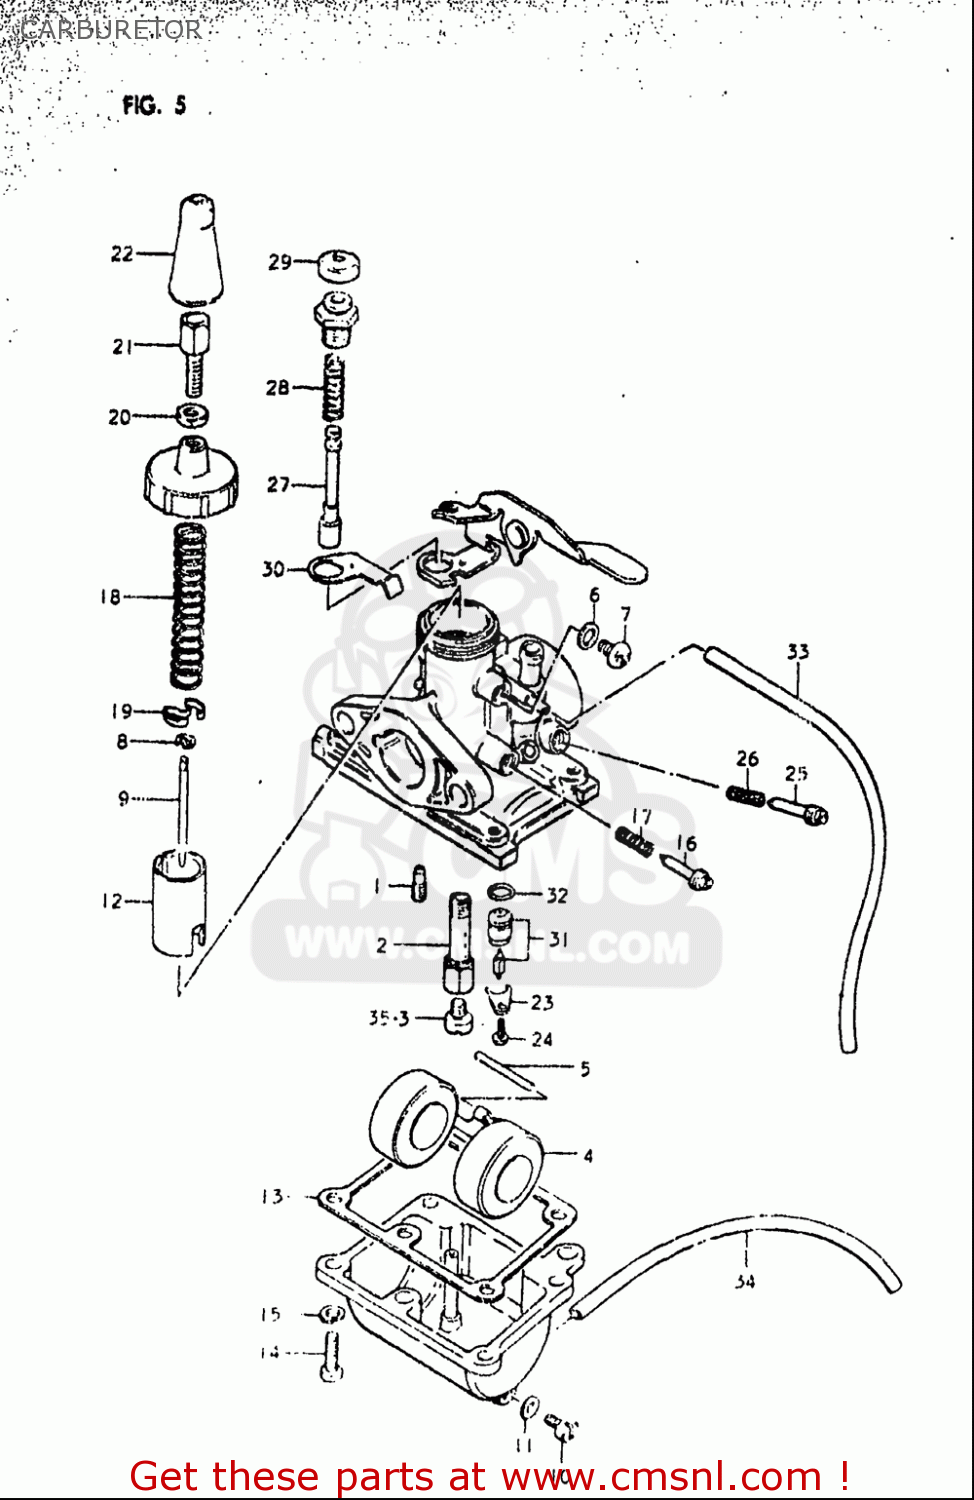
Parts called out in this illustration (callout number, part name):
1	JET,PILOT(15)
2	JET,NEEDLE
3	JET,MAIN(75)
4	FLOAT
5	PIN,FLOAT
6	GASKET,DRAIN PLUG (NAS)
7	SCREW(5X6)
8	CLIP,NEEDLE
10	PLUG
11	GASKET,DRAIN,PLUG (NAS)
13	GASKET,FLOAT CHAMBER (NAS)
14	SCREW 4X16
15	WASHER,LOCK
16	SCREW,THROTTLE STOP
17	SPRING
18	SPRING,THROTTLE VALVE RETURN
19	PLATE
20	NUT
21	ADJUSTER,CABLE
22	CAP
23	PLATE,NEEDLE VALVE FITING
24	SCREW
25	SCREW,AIR
26	SPRING
28	SPRING
31	VALVE ASSY,NEEDLE
32	O RING
33	HOSE(3X5X600)
34	HOSE(3X5X650)
35	JET,MAIN
